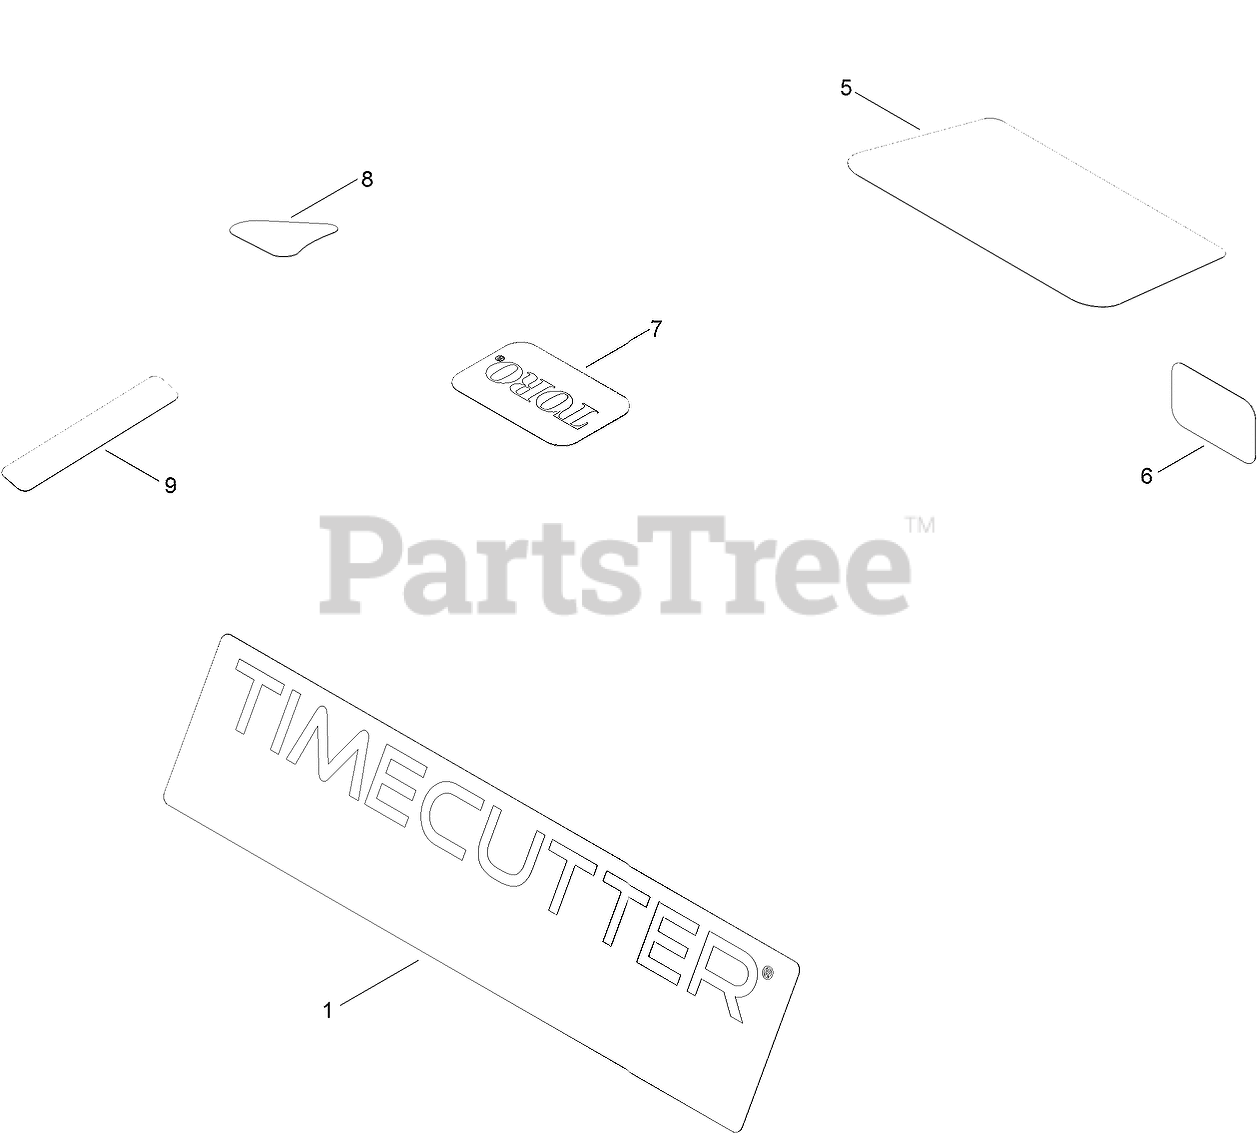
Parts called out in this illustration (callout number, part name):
1	DECAL-TIMECUTTER
5	DECAL-ENGINE
6	PLACARD-INTAKE
8	DECAL-DRAIN, OIL
9	DECAL-SHUTDOWN
